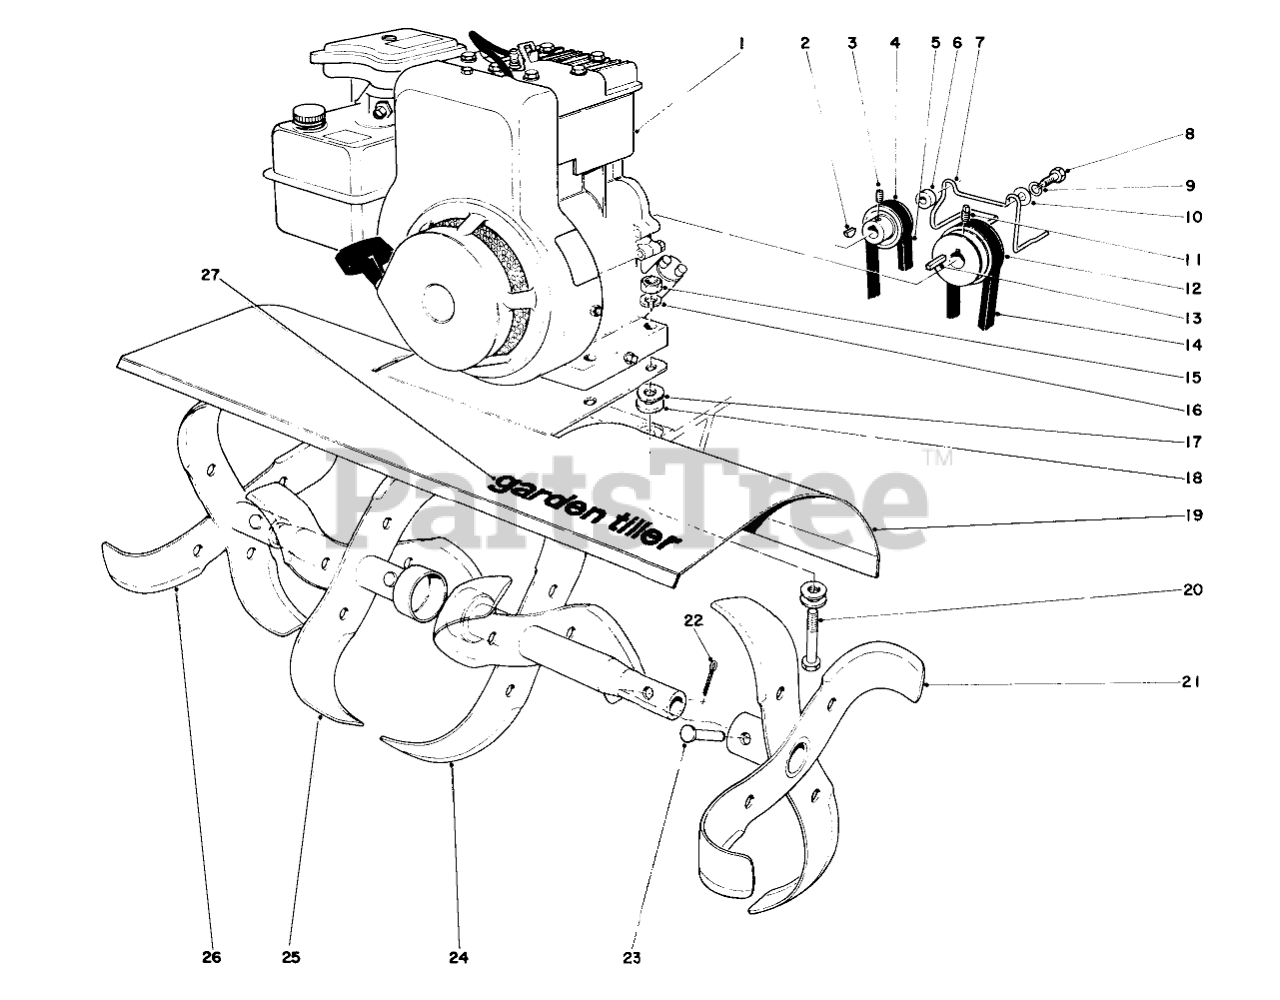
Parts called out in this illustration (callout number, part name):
1	Engine
2	KEY-WOODRUFF
3	SCREW-SET
4	Pulley
5	V-BELT
6	SPACER
7	BELT GUIDE
8	SCREW-HH
9	WASHER-LOCK
10	WASHER-FLAT
11	SCREW-SET, HSH
12	Engine Pulley
13	KEY-SQUARE
14	Belt
15	NUT-HEX
16	WASHER-LOCK
17	WASHER-FLAT
18	WASHER-FLAT
19	Shield
20	SCREW-HH
21	LH OUT SLASH TINE WA
22	PIN-COTTER
23	TINE PIN
24	Inner Tine L.H.
25	Inner Tine R.H.
26	RH OUT SLASH TINE EA
27	Decal
